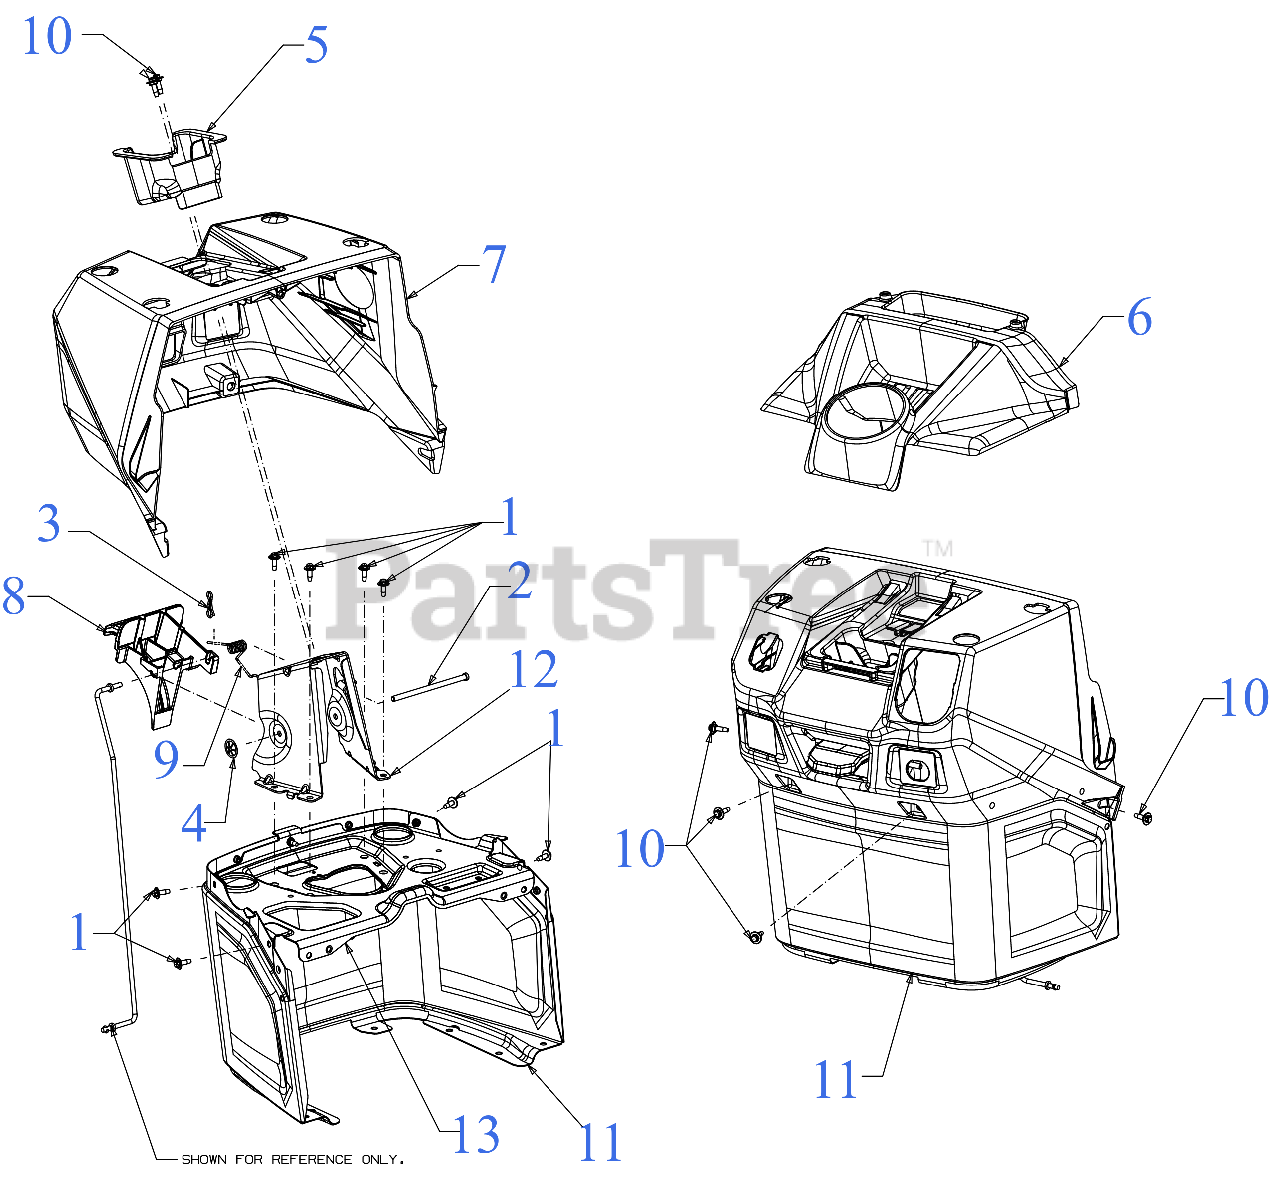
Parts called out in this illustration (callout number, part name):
1	SCREW M6-1 x .625
2	HINGE PIN .25 x 4.50
3	BOW TIE COTTER PIN 1/4-5/16
4	PUSH NUT
5	STEERING SHAFT BEARING
6	UPPER DASH CAP
7	DASH (UPPER)
8	BRAKE LEVER
9	TORSION SPRING .330 ID
10	SHOULDER SCREW M6-1 .368 X.115
13	DASH PLATE
